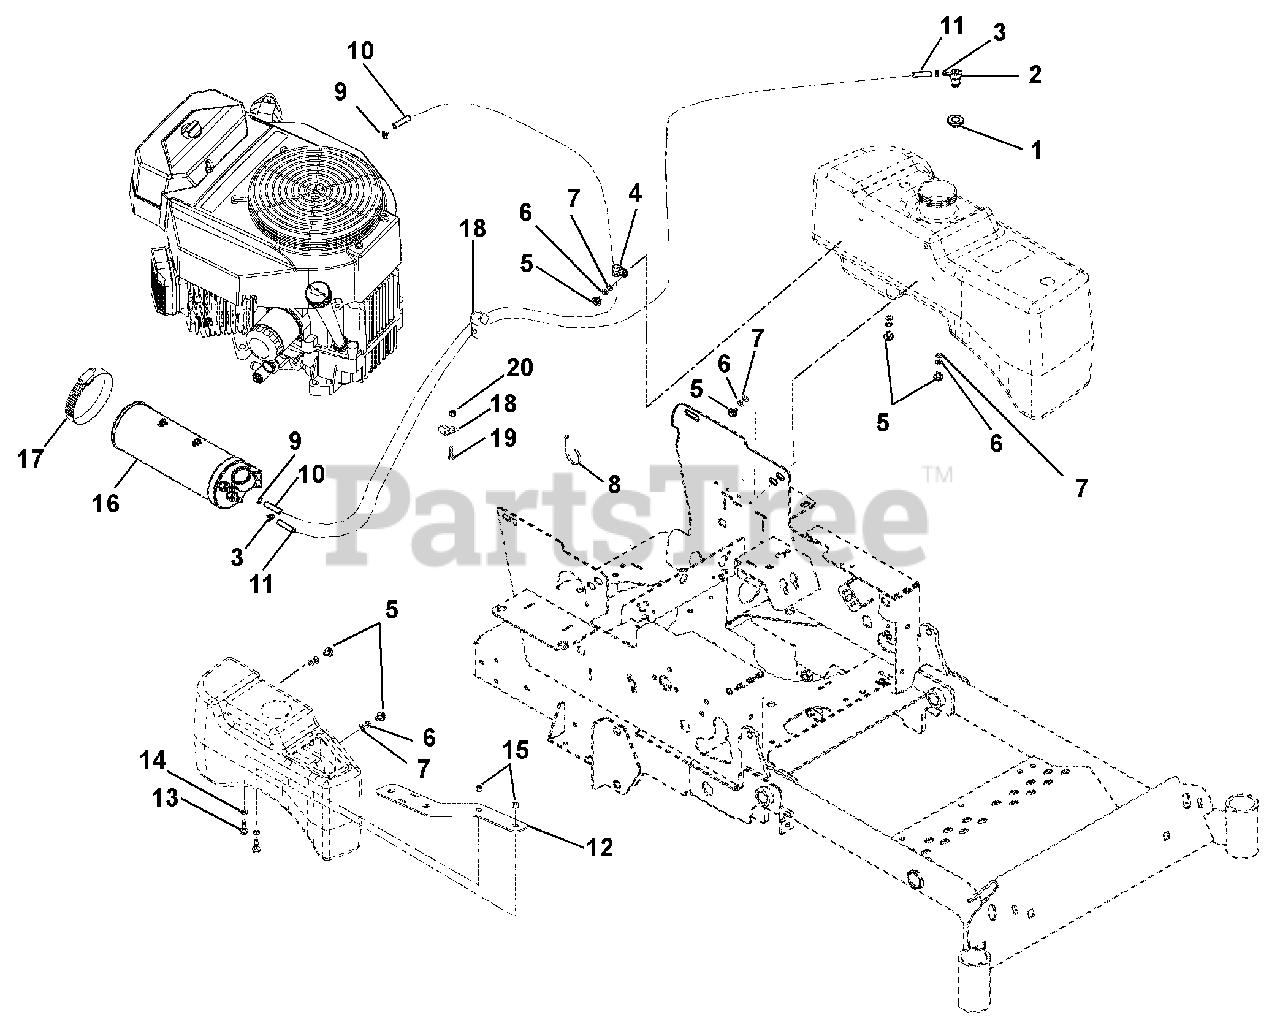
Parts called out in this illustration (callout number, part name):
2	Valve
3	Hose, Clamp
5	Bolt, .31-18 x .62
6	Washer, Locking .31 x .078 Regular
7	Washer, Flat Steel .38 x .875 x .083
8	Tie, Cable LG 5.50
9	Clamp, Spring .188
10	Hose, Fuel .18"
11	Hose, Fuel .25"
12	Plate, Canister Mount
13	Screw, Tapping .25-20 x 1.50 Hex Washer Head Thread Rolling
14	Washer, Flat Steel .281 x 1.000 x .063
15	Nut, Locking Nylon Flange .25-20
16	Canister, Carbon 9.36 Cap
17	Clamp, Hose Worm 2.3/3.2 Stainless Steel #44
18	Clamp, Cushioned Steel
19	Bolt, Hex .38-16 x 1.00 Grade 5
20	Nut, Locking Nylon Flange .38-16
